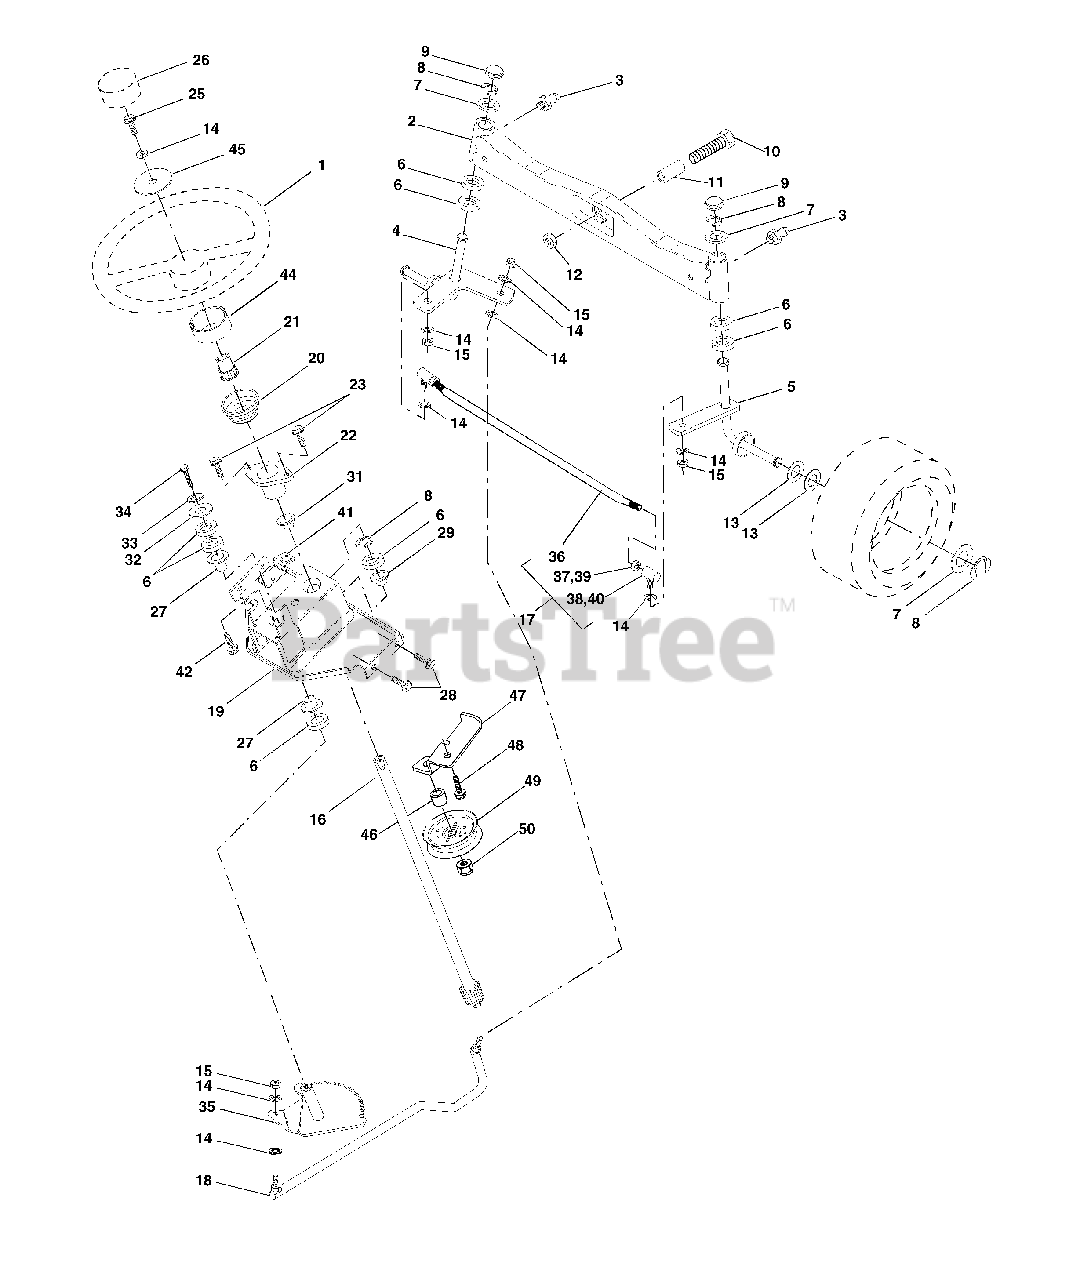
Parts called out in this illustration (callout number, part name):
1	Wheel, Steering
2	Axle Asm., Front
3	Fitting, Grease
4	Spindle Asm, LH
5	Spindle Asm., RH
6	Bearing, Race Thrust Harden
7	Washer 25/32 x 1-5/8 x 16 Ga.
8	Ring, Klip #T5304-75
9	Cap, Spindle
10	Bolt, Fin Hex 5/8-11 x 2-3/4
11	Spacer, Brg. Axle Front
12	Nut, Lock Flange 5/8-11 Unc
13	Washer 25/32 x 1-1/4 x 16 Ga.
14	Washer, Lock Hvy Hlcl Spr 3/8
15	Nut Lock Center 3/8-24 Unf
16	Shaft Asm., Steering
17	Rd Asm. Tie Ball
18	Draglink, Ball Joint Solid Vgt
19	Support Asm., Steering Vgt
20	Boot Steering Stealth
21	Adapter, Wheel Steering
22	Bushing, Strg.
23	Screw
25	Bolt, Fin Hex 3/8-16 x 1 Gr. 5
26	Insert Cap Strg WH
27	Bearing, Col. Strg.
28	Screw Hexwsh thdr 3/8-16 x 3/4
29	Bearing,Flange
31	Bushing, Nyliner Snap
32	Washer 11/32 x 1 x 10 Ga.
33	Washer, Lock Hvy Hlcl Spr 5/16
34	Bolt, Hex Hd 5/16-18 x 3/4
35	Gear, Sector Steering
36	Tie Rod
37	Nut Hex Jam 3/8-24 Unf
38	Joint Asm. Ball RH Service
39	Nut Hex Jam 3/8-24 Unf LH
40	Joint Asm. Ball LH Service
41	Bracket Switch Interlock Vgt 97
42	Screw Thdrol 5/16-18 x 1/2 Tyt
44	Extension Steering
45	Washer 13/32 x 1-1/2 x 11 Ga.
47	Bracket Asm. Idler Stationary
48	Screw 3/8-16 x .75
49	Pulley Idler Flat
50	Nut Lock Flg. 3/8-16 Unc
